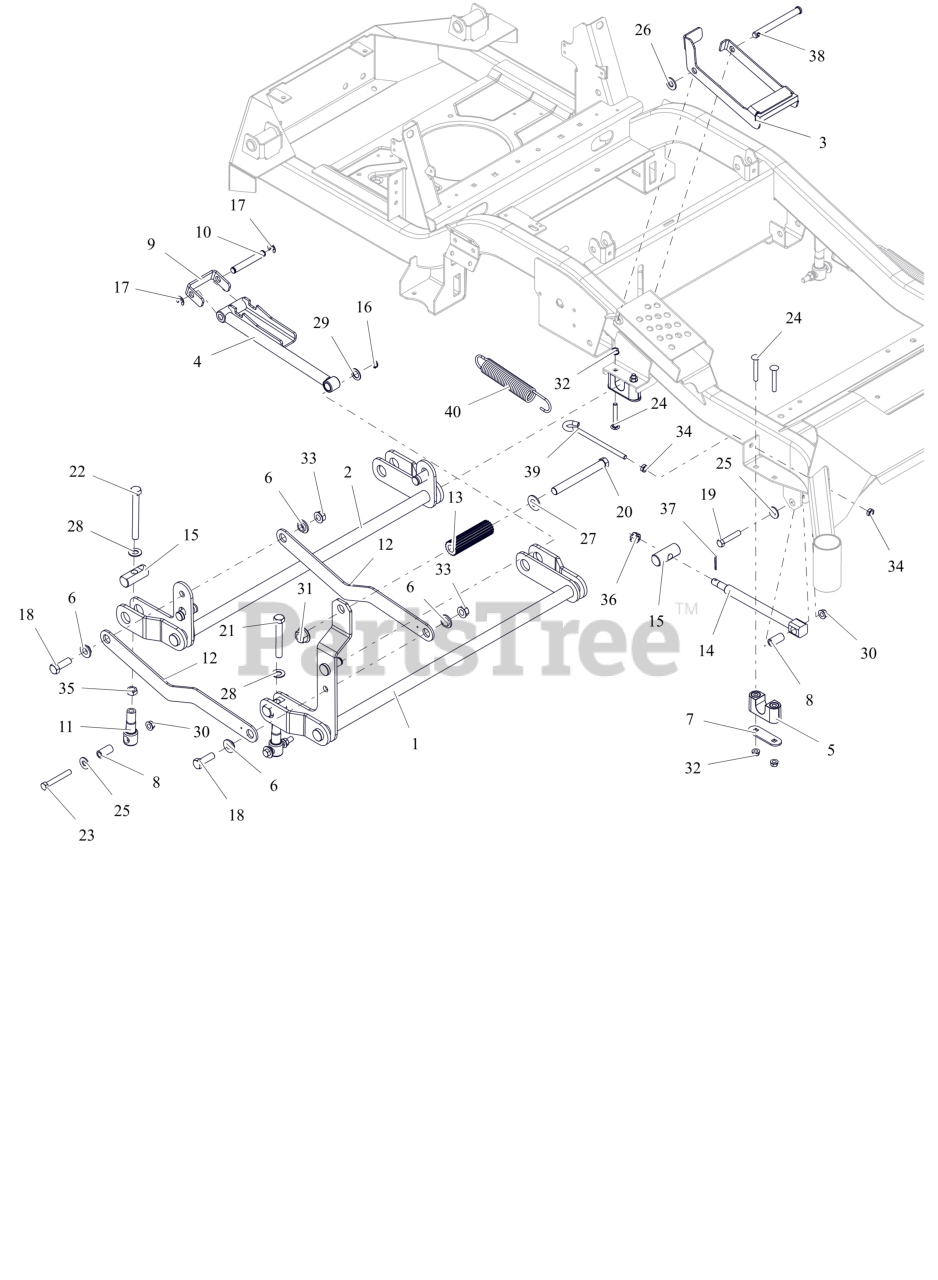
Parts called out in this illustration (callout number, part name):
1	WLDMT, FRONT DECK LIFT PIVOT
2	WLDMT, REAR DECK LIFT PIVOT
3	BRKT, HOC TRANSFER LOCK
4	WLDMT, HOC ARM
5	ASM-BUSHING, DECK LIFT
6	BSHG-FLG .515X.750X.395X1.120
7	PLATE, BEARING SUPPORT
8	SPACER, DECK LEVELING
9	BRKT, HOC LINE
10	ROD, HOC PIVOT
11	LINK, DECK LIFT FORMED
12	LINK, DECK LIFT
13	ROD, FOOT PEDAL (BLACK)
14	DRAG,LINK-HD
15	PIN, DECK LIFT
16	RG-RTNG-EXT .625X.050
17	RG-RTNG-EXT .500X.042 (E)
18	BLT,HEX .50-13X1.50 G5 ZCC
19	BLT,HEX .38-16X2.00 G5 ZCC
20	BLT, HEX .62-11X5.50 G5 FBP
21	BLT, HEX .50-13X3.50F G5 ZCC
22	BLT, HEX .50-13X4.50F G8 ZCC
23	BLT, HEX .38-16X2.75 G8 ZCC
24	BLT, RHSSN.31-18X2.25 G5 ZCC
25	WSHR,FLT .438X1.00X.083 ZCC
26	WSHR,FLT .531X1.062X.095 ZCC
27	WSHRFLT 5/8SAE CARBHARD FBP
28	WSHR, FLT .557X1.040X.102 ZCC
29	WSHR, FLT .630X1.005X.062 ZCC
30	NUT-LK-TOP-FLG .38-16 ZC120
31	NUT,FLG-TOP LK .625-11 FBP
32	NUT,LK-CTR-FLG .31-18 GF ZCC
33	NUT-LK-TOP-FLG .500-13 GF ZCC
34	NUT-JAM .375-16 G2 ZCC
35	NUT-JAM .500-13 G2 ZCC
36	NUT-SL .50-13
37	PIN,CTR.12X1.25EXTPRSQCT ZC120
38	PIN-SLIC .50X4.97X4.55 -ZCC
39	BOLT,.38-16 X 5.25-.62 DIA EYE
40	SG-TENS .162X1.25X8.25 WLD 25
